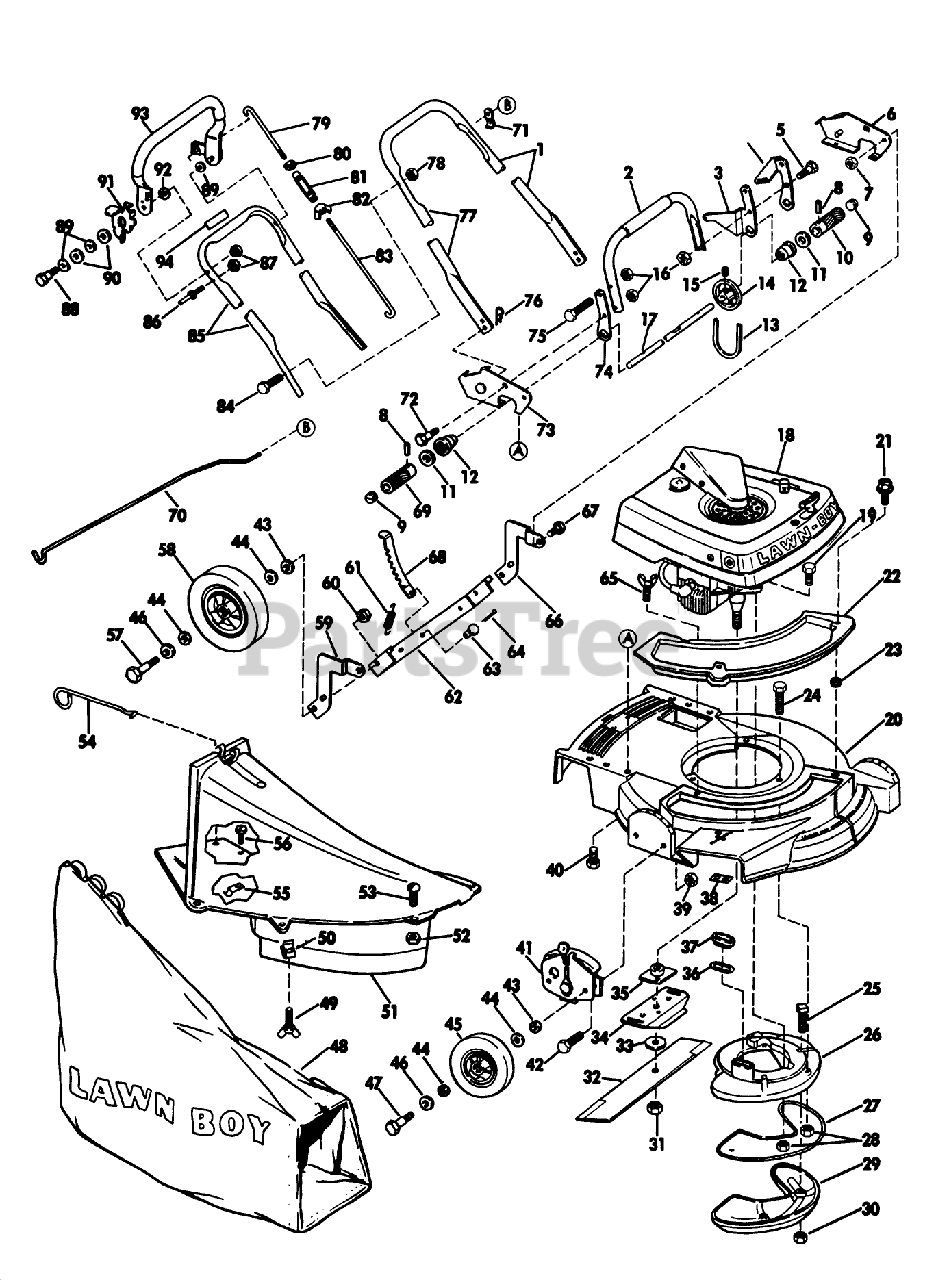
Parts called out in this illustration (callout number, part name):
9	GREASE PLUG
10	LEFT ROLLER
21	SCREW SEMS TRM HEX HD
30	LOCKNUT E
31	NUT-BLADE
35	PLATE AND COLLAR ASM
36	GASKET S
43	WASHER WROUGHT
47	BOLT WHEEL
48	89802 LB WHOLE GOODS
50	SPEED NUT ARDEN
51	Skirt Assembly
60	LOCKNUT
61	SPRING N.A.S
67	BOLT-SHOULDER
70	ROD & CLIP
72	BOLT PIONEER
76	HAIR PIN
88	BOLT PIONEER
89	WASHER M
